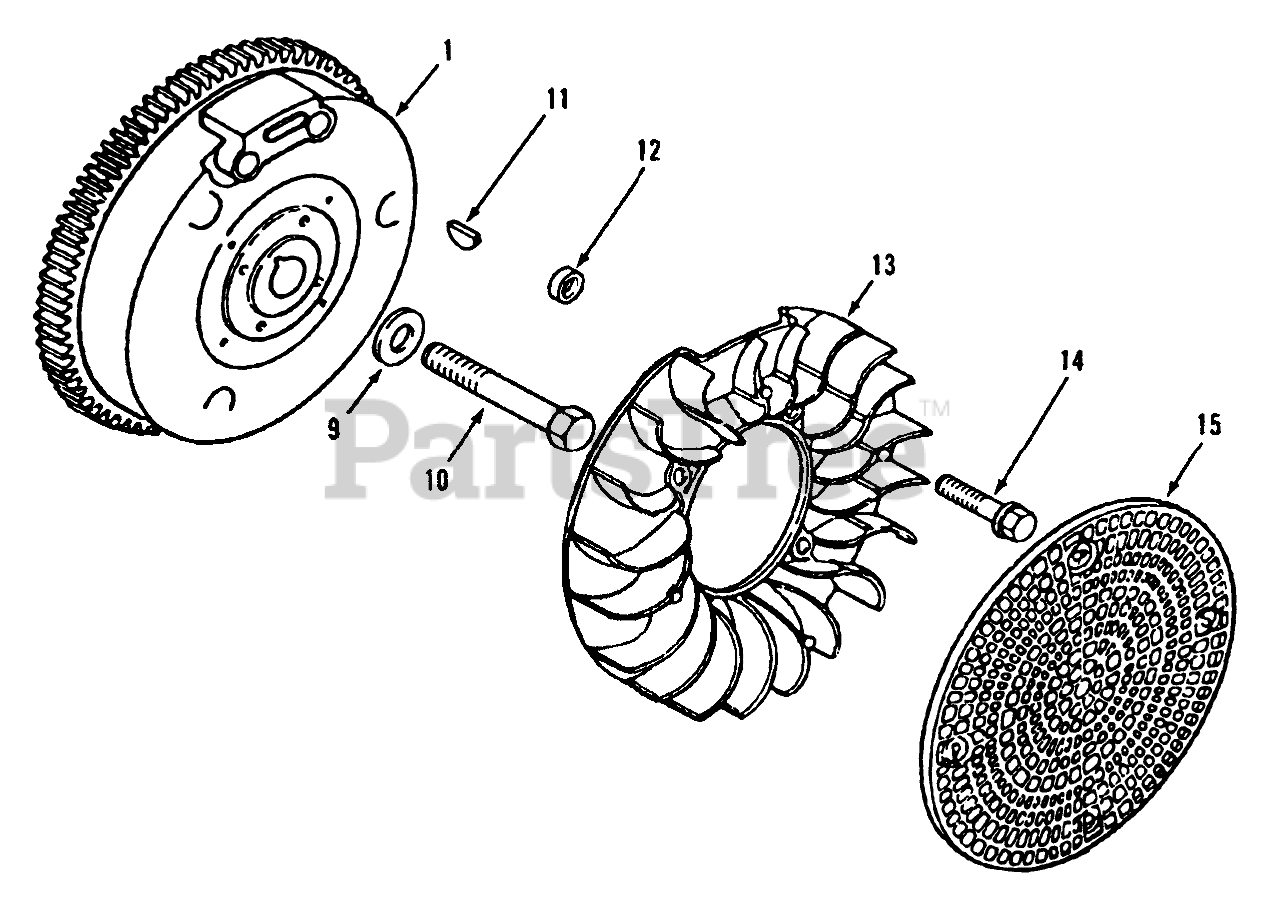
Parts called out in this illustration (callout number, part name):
1	Flywheel
9	Washer
10	Screw
11	Key-Woodruff
12	Spacer 17/64 ID, 3/8 OD 15/64 Lg.
14	Screw-Hex. Hd.
15	Screen
